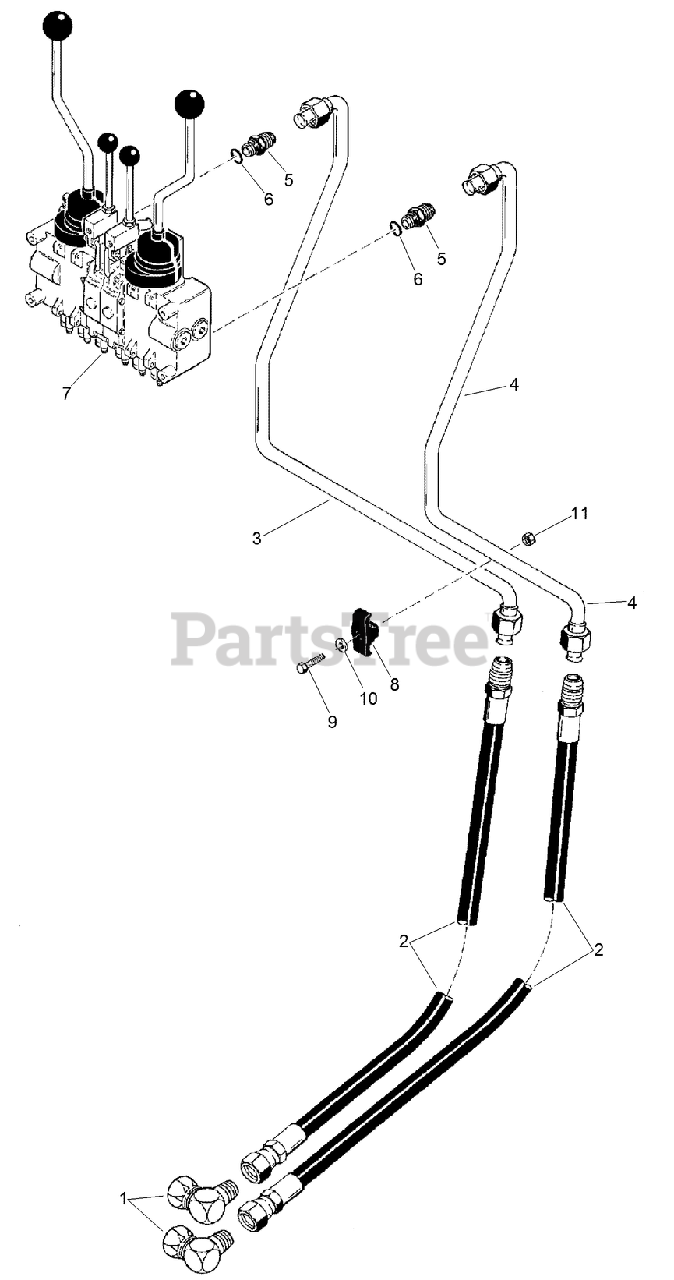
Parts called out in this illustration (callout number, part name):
1	FITTING-ELBOW, 90
2	HOSE-1028 mm (40-1/2 inch) long, backhoe control valve supply and return
3	TUBE-backhoe control valve supply
4	TUBE-backhoe control valve return
5	CONNECTOR-Str Thd 3/4, 37FL-ORB 5/8
6	O-RING
7	VALVE-Backhoe, w/Special Low Leak Spools
8	CLAMP-Tube
9	BOLT-Hex Hd 3/8 x 2 GR5 ZND
10	WASHER-FLAT
11	NUT-HEX
